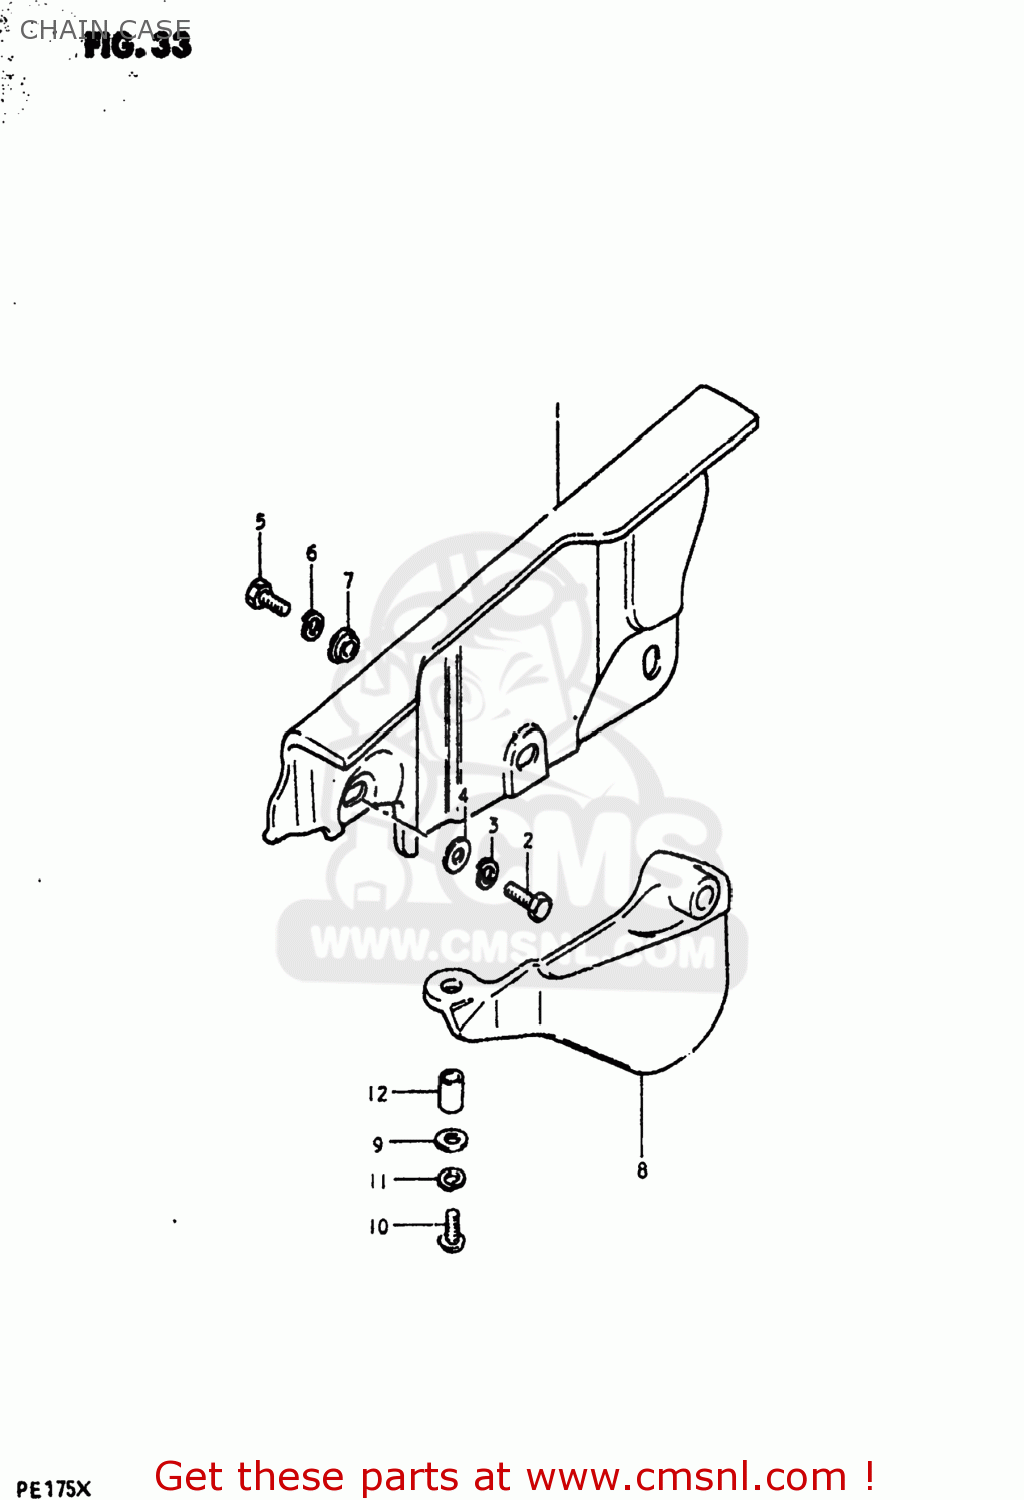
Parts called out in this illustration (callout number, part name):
1	CASE,CHAIN
2	BOLT, UPPER
3	LOCK WASHER
4	WASHER(6.5X18X1)
5	BOLT
6	LOCK WASHER
7	WASHER
8	RUBBER,CHAIN CASE,LOWER
9	WASHER(6.5X18X1)
10	SCREW 6X12
11	LOCK WASHER
12	SPACER (6.1X8X5.2)
